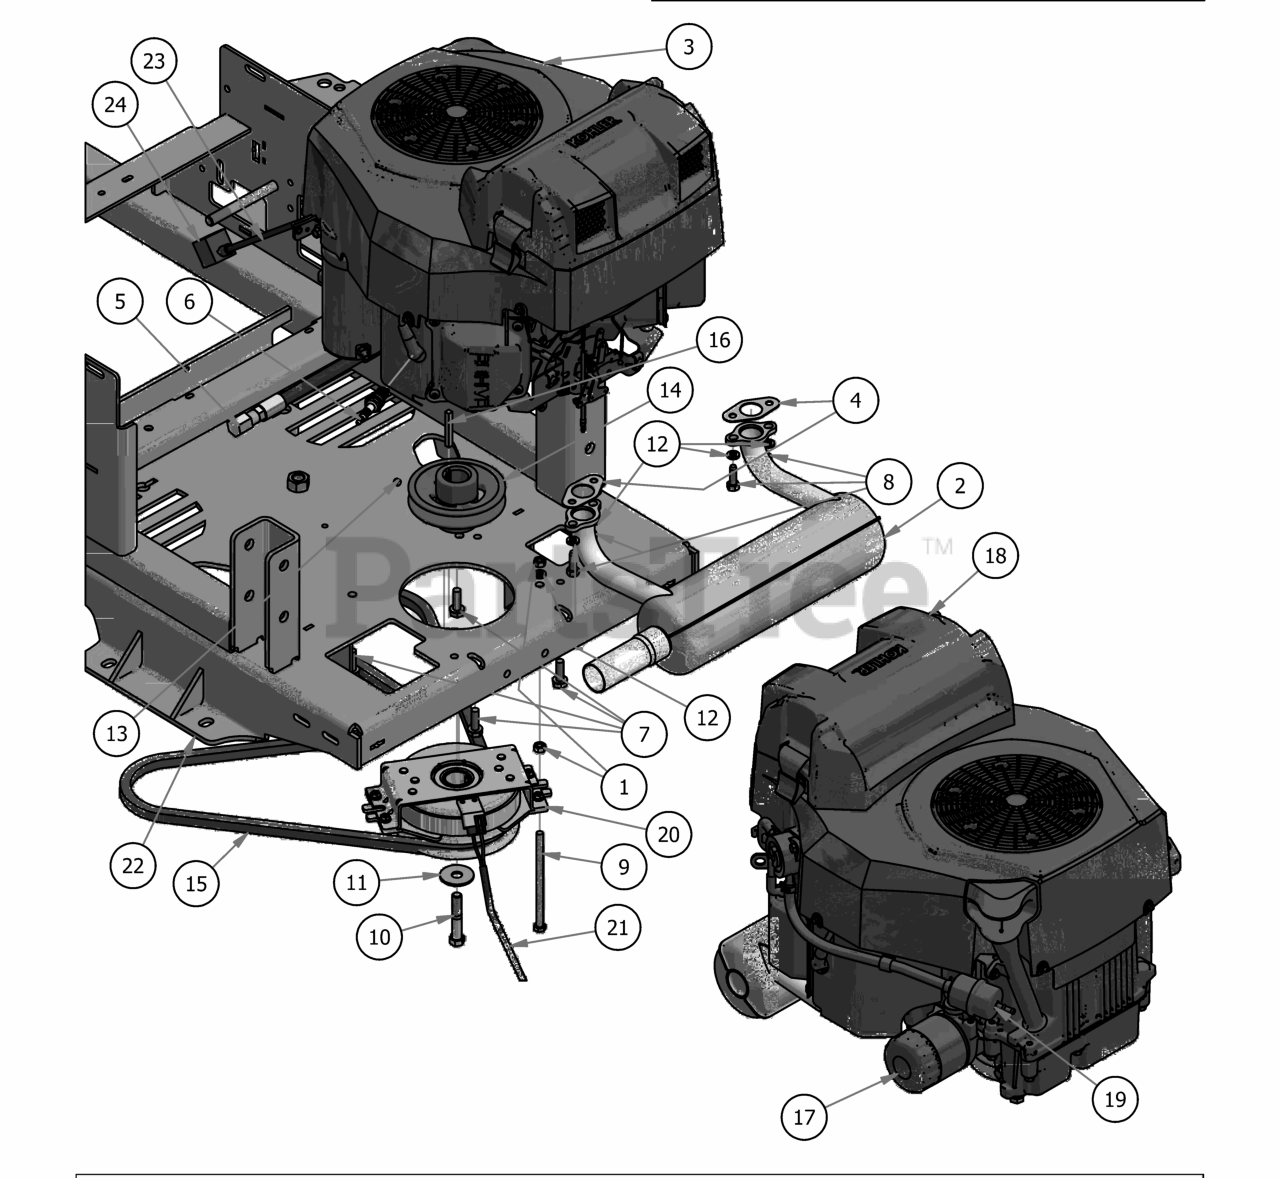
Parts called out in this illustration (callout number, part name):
2	Kohler Muffler
3	Kohler 747cc Engine
4	Exhaust Gasket
5	Oil drain Valve
6	Spark Plug
7	3/8 x 1 1/8 bolt
8	5/16-18 x 1 GR 5 Hex Bolt Zinc
9	5/16-18 x 5-1/2 GR 5 Hex Bolt
10	7/16"-20 x 2.5" Hex Bolt Gr. 8
11	1/2" Belleville Washer
12	5/16" Lock Washer
13	5/16 Set Screw
14	4 3/4 Motor Pulley
15	75.8 Pump Belt
16	1/4 x 2 Square key Stock
17	725 & 747 Kohler Oil Filter
18	725 Kohler air filter
19	Universal Inline Fuel Filter
21	Clutch Pigtail
22	2018 Maverick Frame
23	Ground Cable
24	Black Boot For Ground Cable
